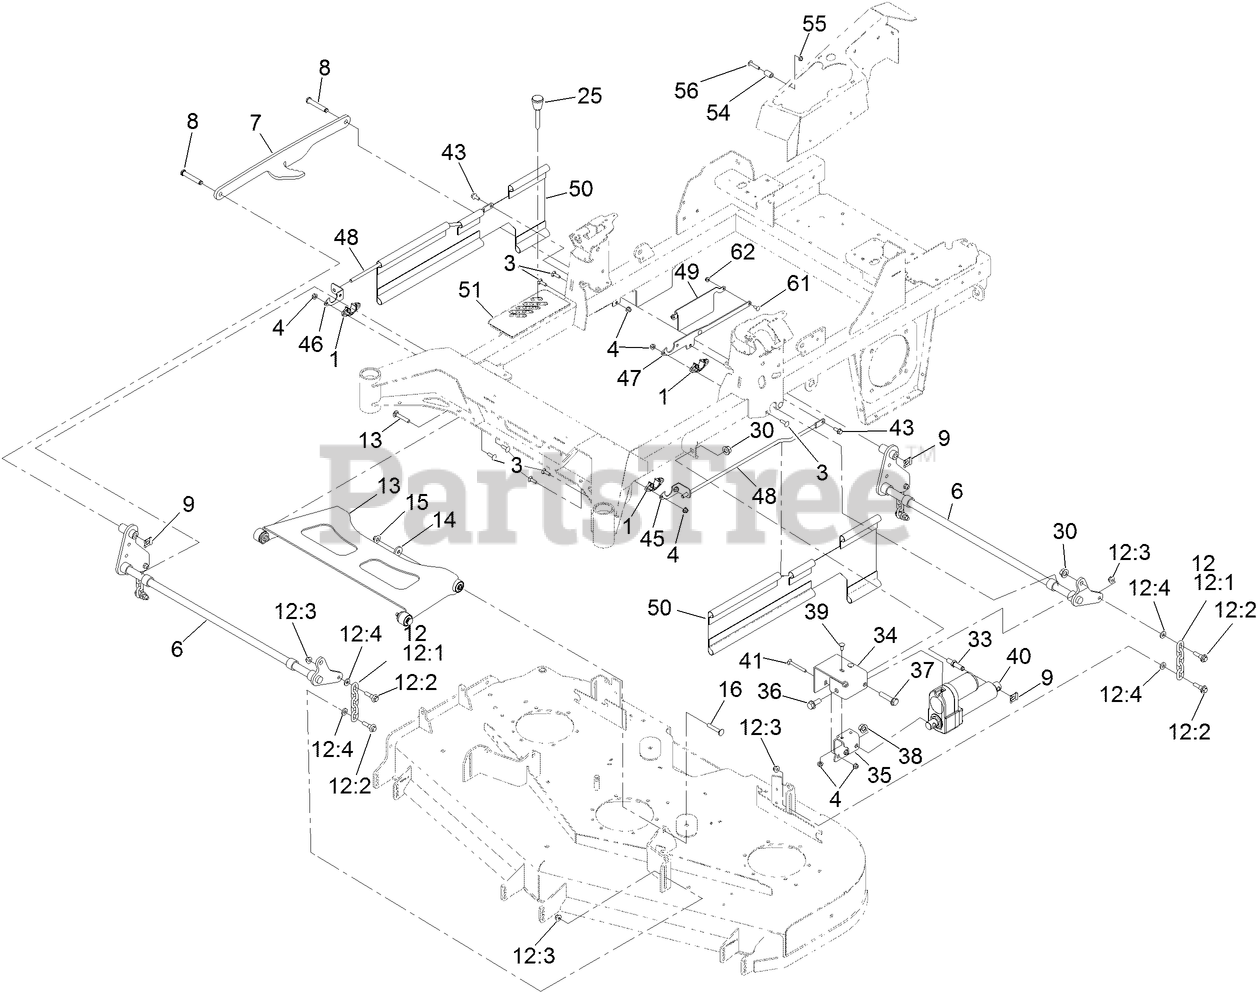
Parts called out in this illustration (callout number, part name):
1	BUSHING-FLANGE
3	SCREW-CARR
4	NUT-HF, NI
6	DECK LIFT SHAFT ASM [BLACK]
7	LINK-LIFT
8	PIN-CLEVIS
9	CLIP-PIN
12	DECK CHAIN ASM
12:1	CHAIN-LIFT, DECK
12:2	BOLT-SHOULDER
12:3	NUT-HF, NI
12:4	SPACER
13	ASM-DECK STRUT W/ BUSHINGS
14	WASHER
15	NUT-FLANGE, NI
16	SCREW-CARR
25	PIN-HOC
30	NUT-LOCK
33	PIN-PIVOT, ACTUATOR
34	BRACKET-MOUNT, OUTER
35	BRACKET-MOUNT, INNER
36	SCREW-HHF
37	SCREW-HHF
38	NUT-LOCK
39	BOLT-CARR
40	ACTUATOR-LINEAR
41	SCREW-CARR
43	SCREW-HHF
45	BRACKET-MOUNT, UPPER FRONT (LH)
46	BRACKET-MOUNT, UPPER FRONT (RH)
47	BRACKET-MOUNTING, UPPER
48	ROD-SUPPORT, UPPER
49	BRACKET-FLAG
50	GUARD-SIDE
51	DECAL-HOC, MM
54	SPACER
55	NUT-LOCK, NI
56	SCREW-TORX
61	SCREW-CARR
62	NUT-HF
